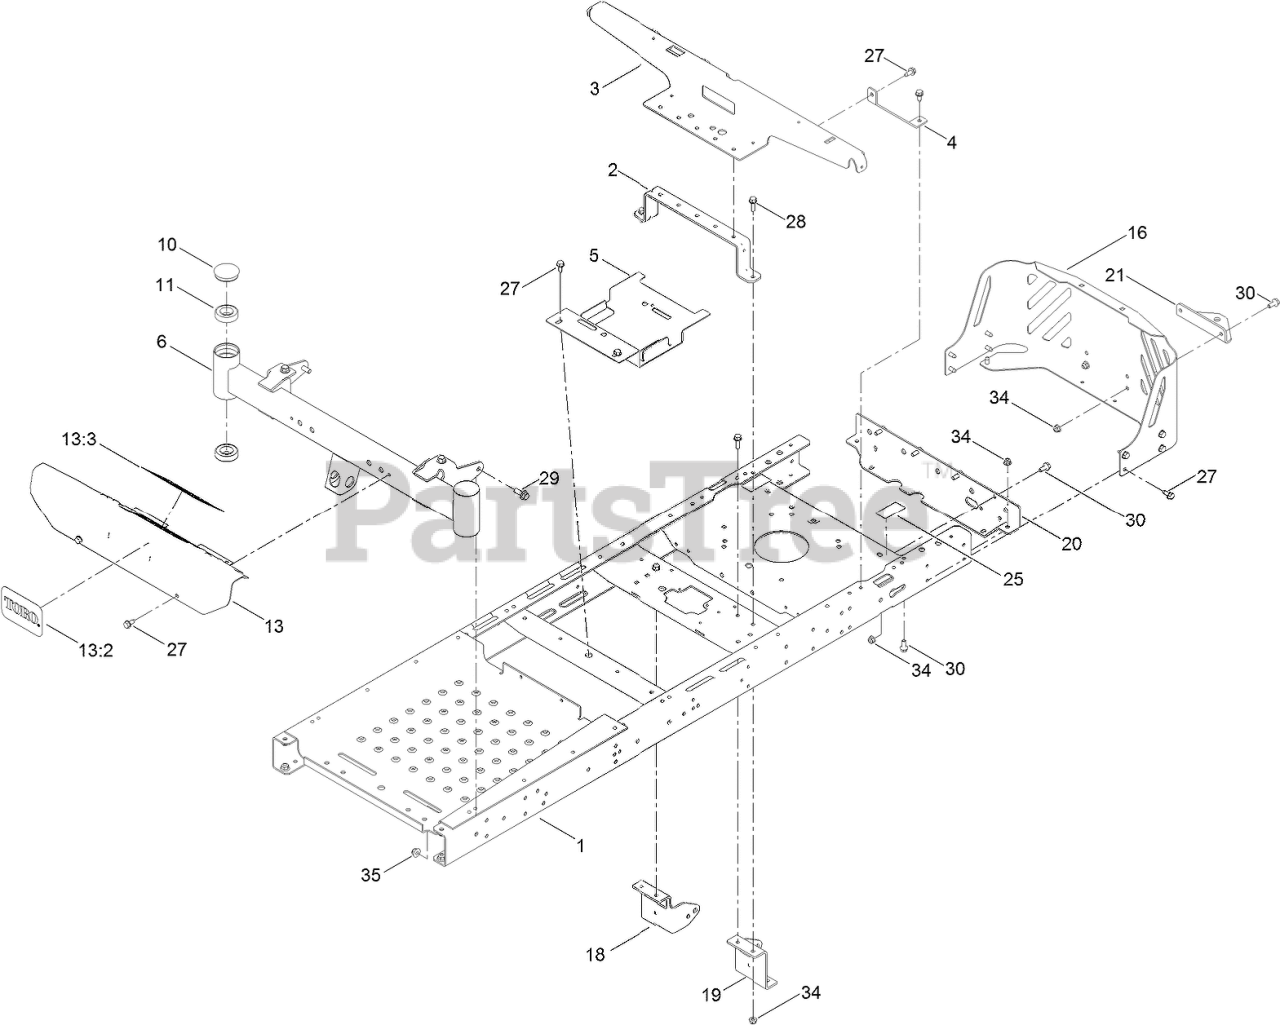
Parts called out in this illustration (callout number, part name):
1	FRAME ASM
2	BRACE-SEAT, REAR (NARROW)
3	SUPPORT-POD
4	SUPPORT-TANK, REAR
5	BRACKET-BATTERY
6	AXLE-FRONT, NARROW
10	CAP-GREASE
11	BEARING-BALL
13	FOOTREST ASM
13:3	DECAL-DANGER
16	GUARD-ENGINE, NARROW
18	MOUNT-HYDRO, FRONT (RH)
19	MOUNT-HYDRO, FRONT (LH)
20	CROSSMEMBER-REAR, NARROW
21	BRACKET-HITCH
25	DECAL-BYPASS
27	SCREW-HWHTF
28	SCREW-HHF
29	SCREW-HHF
30	SCREW-HHF
34	NUT-HF, NI
35	NUT-HF, NI
